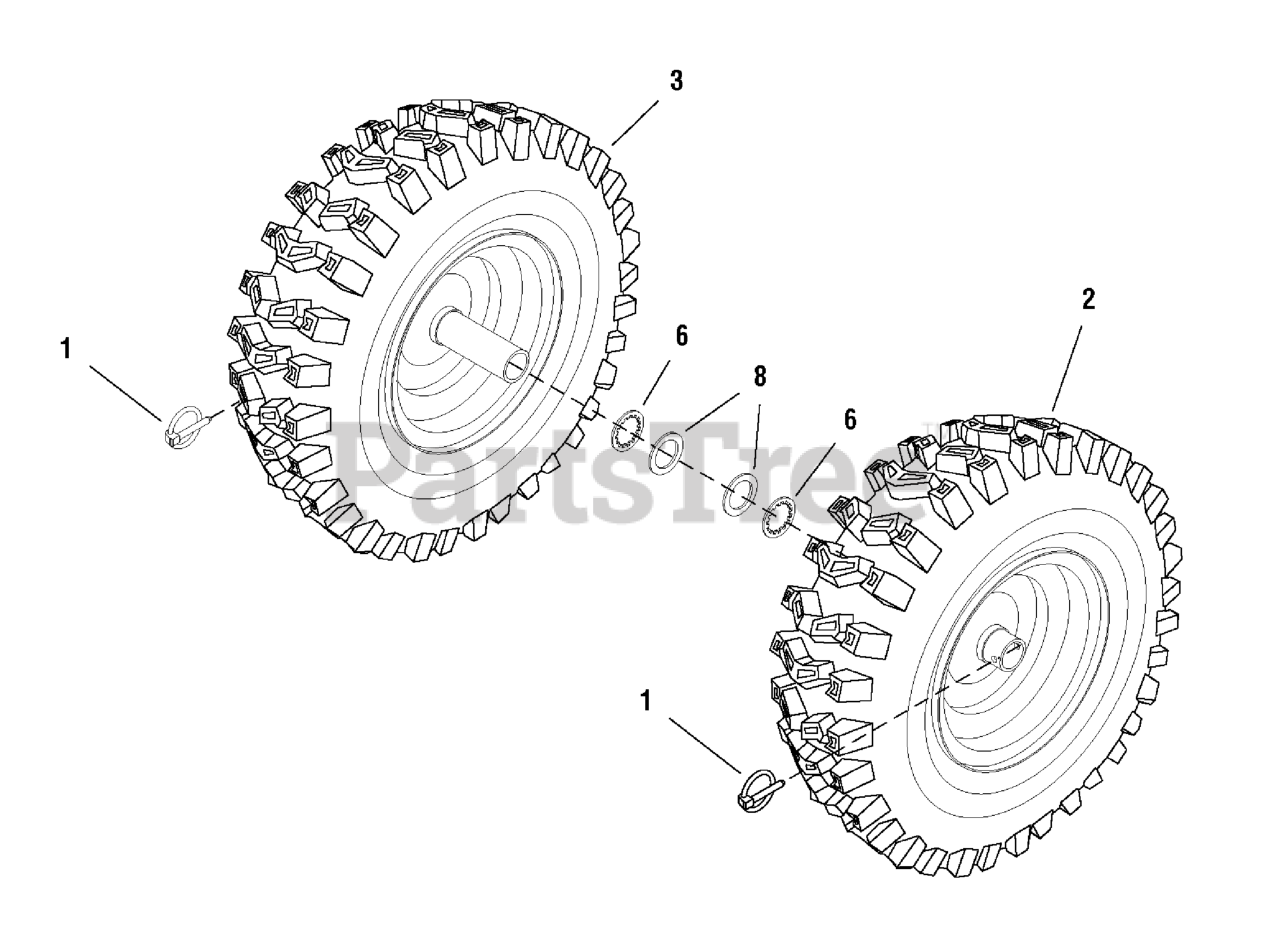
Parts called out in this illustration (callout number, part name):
1	PIN, Klik
2	WHEEL & TIRE ASSEMBLY, L.H. SNOW XTRAC 16 x 4.8-8
2	WHEEL & TIRE ASSEMBLY, L.H.
3	WHEEL & TIRE ASSEMBLY, R.H. SNOW XTRAC 16 x 4.8-8
3	WHEEL & TIRE ASSEMBLY, R.H.
6	RETAINING RING, Extension Self Lock
8	WASHER, FLAT .765 x 1.12 x .06 YZ
